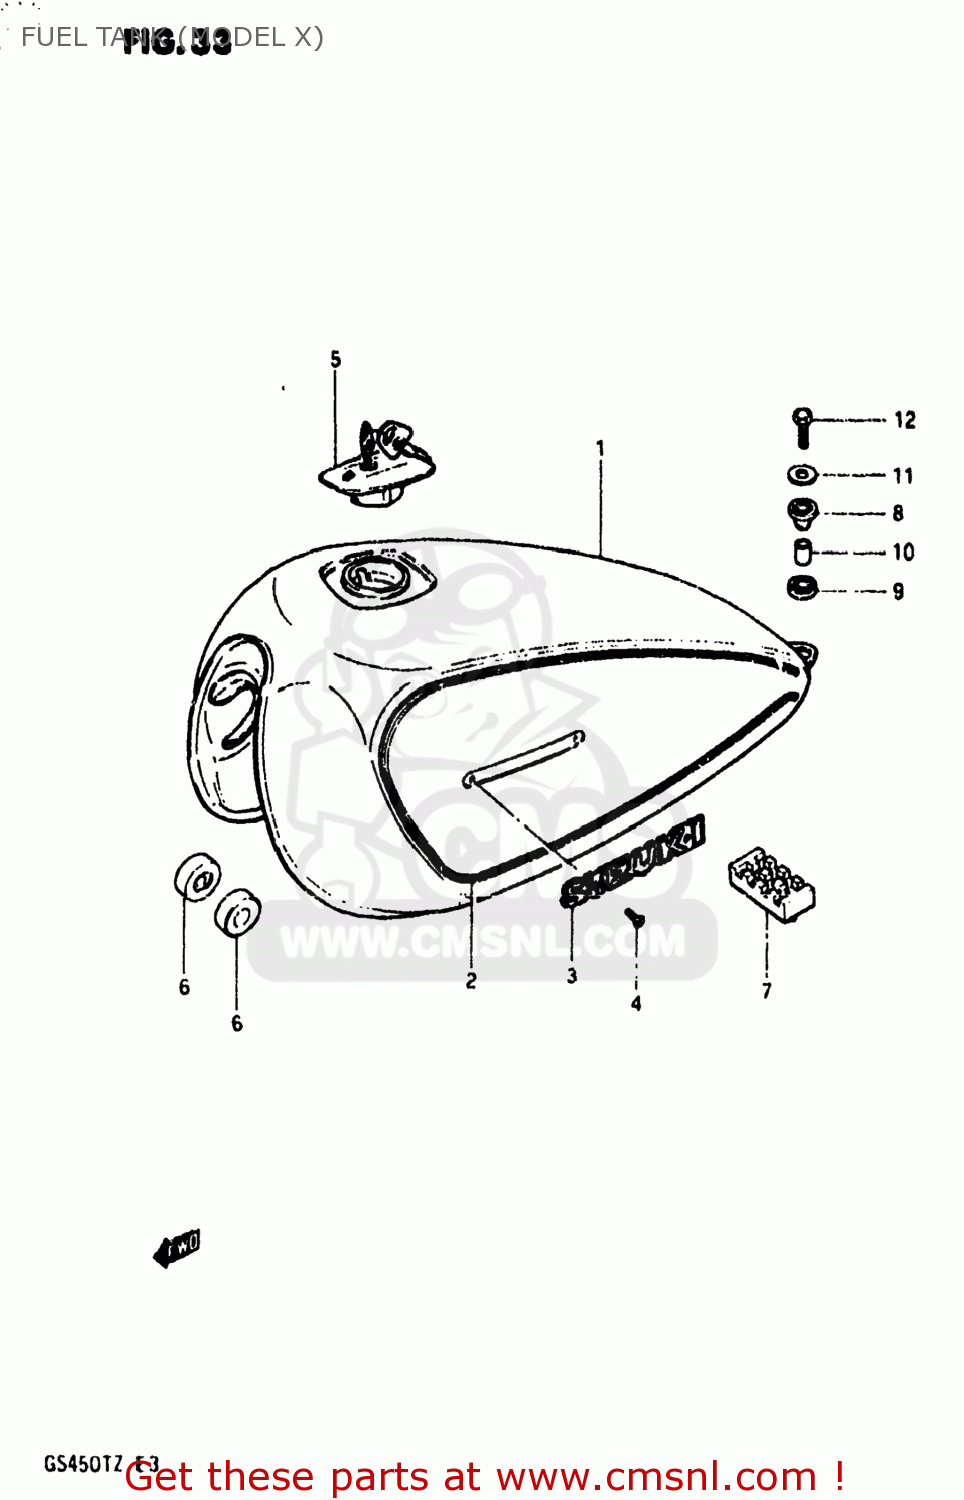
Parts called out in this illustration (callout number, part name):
1	TANK ASSEMBLY,FUEL
2	TAPE SET,FUEL TANK
3	EMBLEM,FUEL TANK
4	SCREW 3X6
5	CAP SET,FUEL TANK
6	CUSHION
7	CUSHION,FUEL TANK CTR
8	CUSHION
9	CUSHION
10	SPACER
11	WASHER (6.5X24X1.6)
12	BOLT
